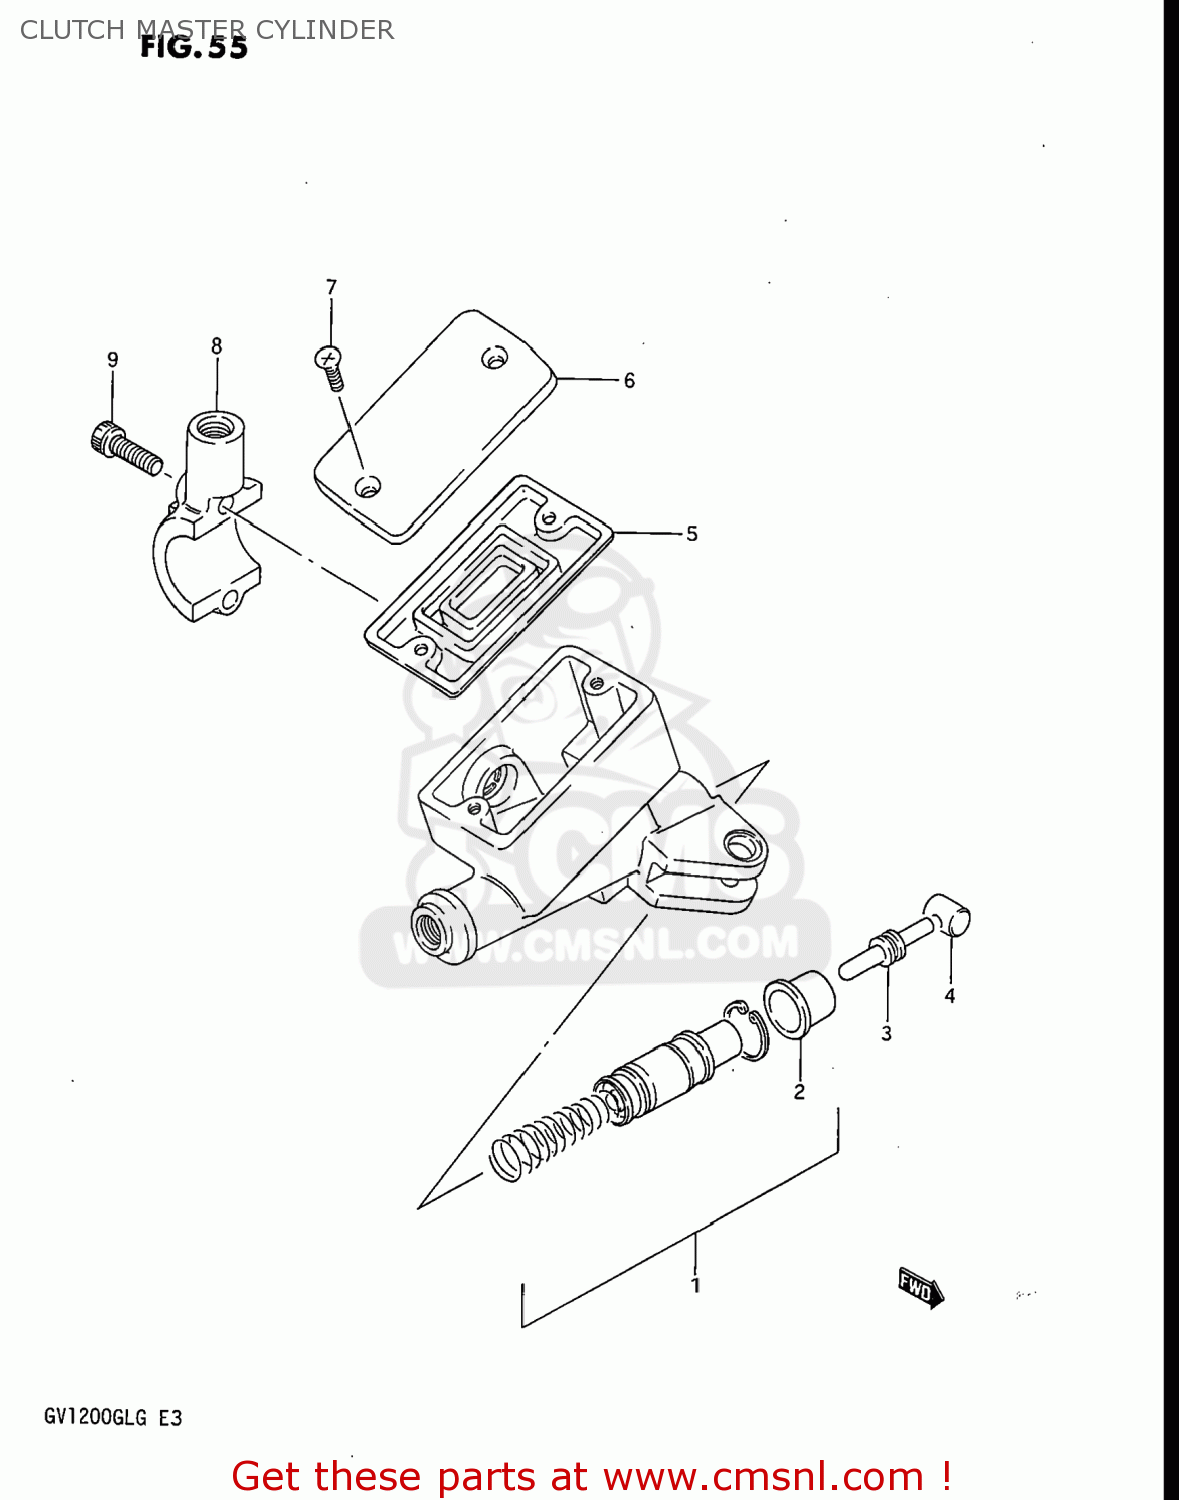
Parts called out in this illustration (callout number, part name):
1	PISTON & CUP SET
2	BOOT
3	ROD,PUSH
4	BUSH
5	6
6	CAP
7	SCREW
8	HOLDER
9	BOLT
